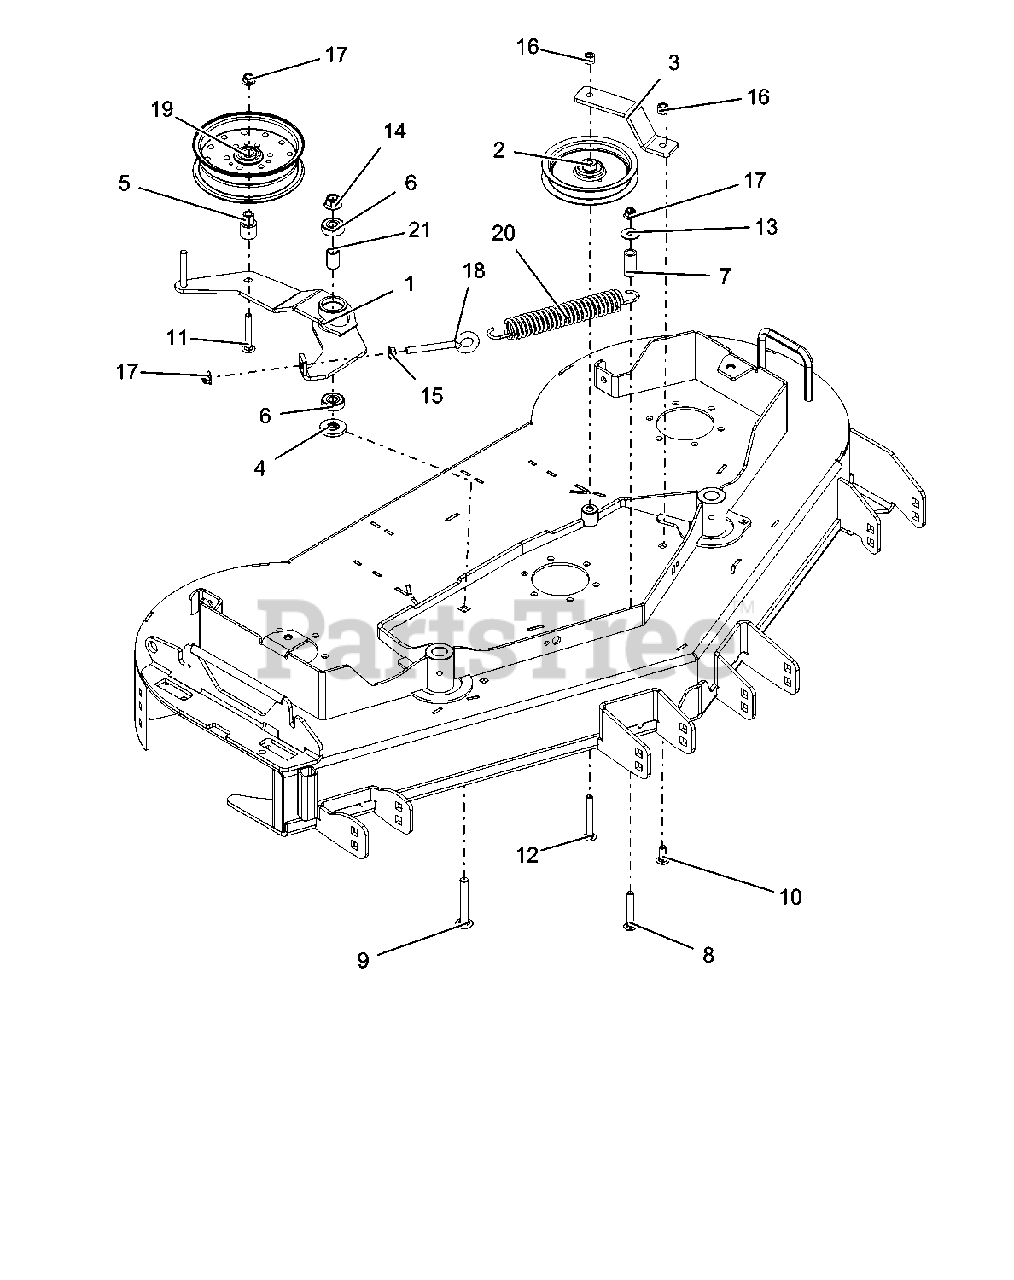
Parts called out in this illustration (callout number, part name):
1	WLDMT, IDLER ARM 52 FLWLK (BLACK)
2	IDLER, FLAT - 5.00" X .75"
3	STRAP, IDLER 48/52 WALK-BLACK
4	SPACER, IDLER ARM
5	SPCR, IDLER
6	BRG-BALL .500X1.375X.44
7	BSHG-SLV .500X.750X1.560
8	BLT-RHDSSQNK .38-16X2.50 G5YZ
9	BLT-RDHDSQSHNK .50-13X3.25 YWZC
10	BLT-RDHDSHSQNK.38-16X1.0 G5YZ
11	BLT-RDHDSQNK .38-16X2.50 G5 Y
12	BLT-RDHDSQNK .38-16X3.00 G5 YWZC
13	WSHR-FL-STL .375X1.125X.065YWZ
14	NUT-LK-NYL-FLG .50-13 YWZC
15	@NUT-SPNLK-FLG .375-16 YWZC
16	NUT-LK-NYL .38-16 YWZC
17	NUT-LK-NYL-FLG .38-16 YWZC
18	BOLT, EYE .38-16X4.50 .75 DIA
19	PULLEY, FLAT IDLER 6.00 X .635
20	SPRG, EXTENSION
21	SPACER, .510 X .750 X 1.148
